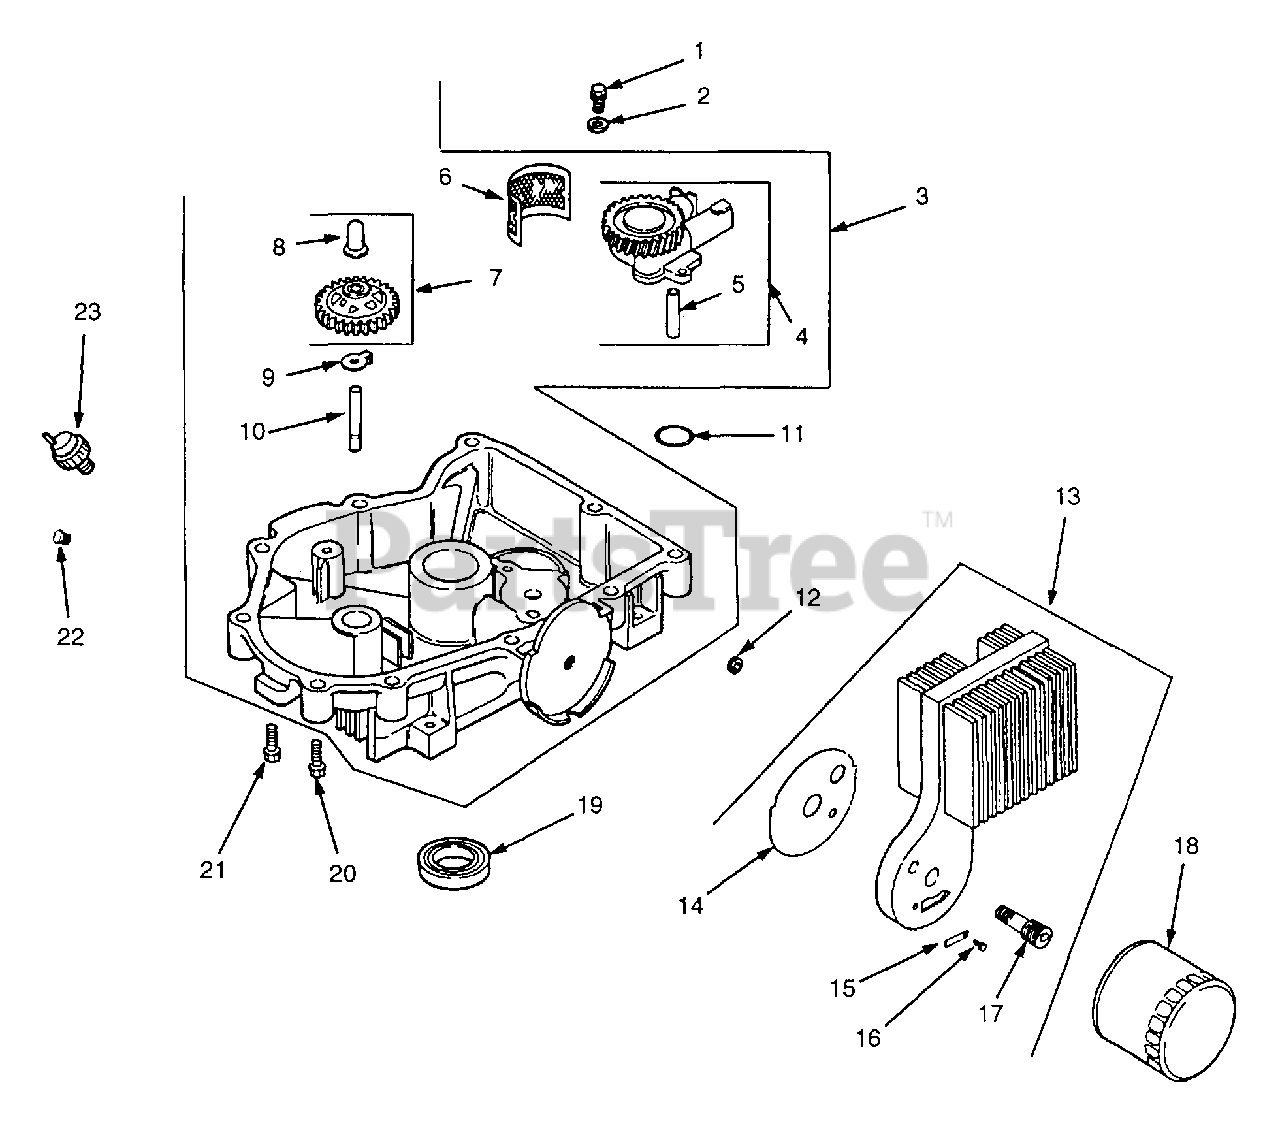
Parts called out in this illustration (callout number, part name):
1	Screw, Hex Flange, M6 x 1.0 x 25
2	Washer, 6mm
3	Pan Ass'y, Oil
4	Oil Pump Ass'y
5	Tube, Oil Pickup
7	Gear Kit, Governor w/Pin
8	Pin, Governor Regulating
9	Tab, Locking
10	Shaft, Governor Gear
12	Plug, Hex Cntrsk, 3/8
13	Oil Cooler Kit
14	Gasket, Oil Filter Adapter
15	Reed, Oil Relief
16	Screw, Hex Flange, M4 x 0.7 x 10
17	Nipple, Oil Filter
18	Filter, Oil
19	Seal, Oil (PTO End)
20	Screw, Hex Flange, M8 x 1.25 x 45
21	Screw, Hex Flange, M8 x 1.25 x 45
22	Plug, Hex, 3/8
23	Switch, Oil Pressure
